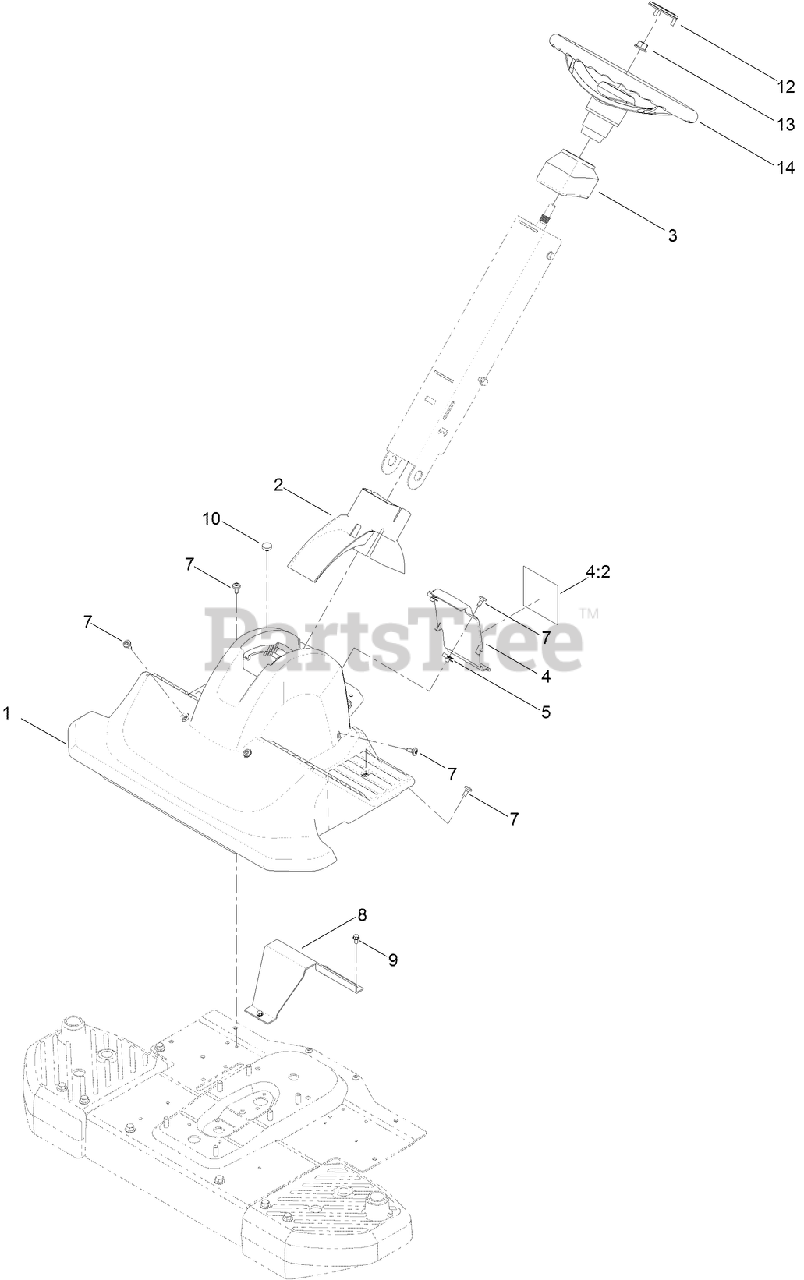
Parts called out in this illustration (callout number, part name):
1	SHROUD-STYLING, FRONT
2	COVER-PIVOT, COLUMN
3	CAP-COLUMN
4	REAR COVER AND DECAL ASM
4:2	DECAL-DANGER
7	SCREW-SHOULDER
8	SUPPORT-FOOTREST
9	SCREW-HWH
10	BUMPER
12	CAP-WHEEL, STEERING
13	NUT-LOCK
14	WHEEL-STEERING
